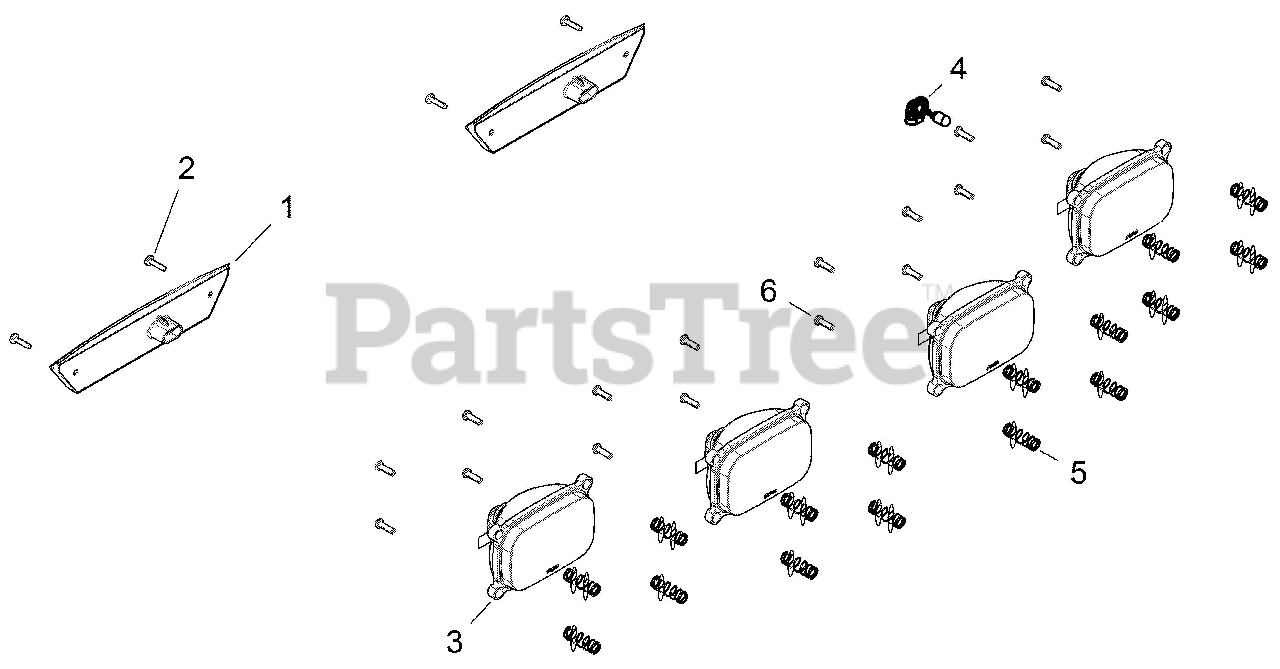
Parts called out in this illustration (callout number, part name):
1	ASM-TAILLIGHT
3	ASM-HEADLIGHT
4	BULB-HEADLIGHT,50 WATT
5	SPRING, HEADLIGHT
